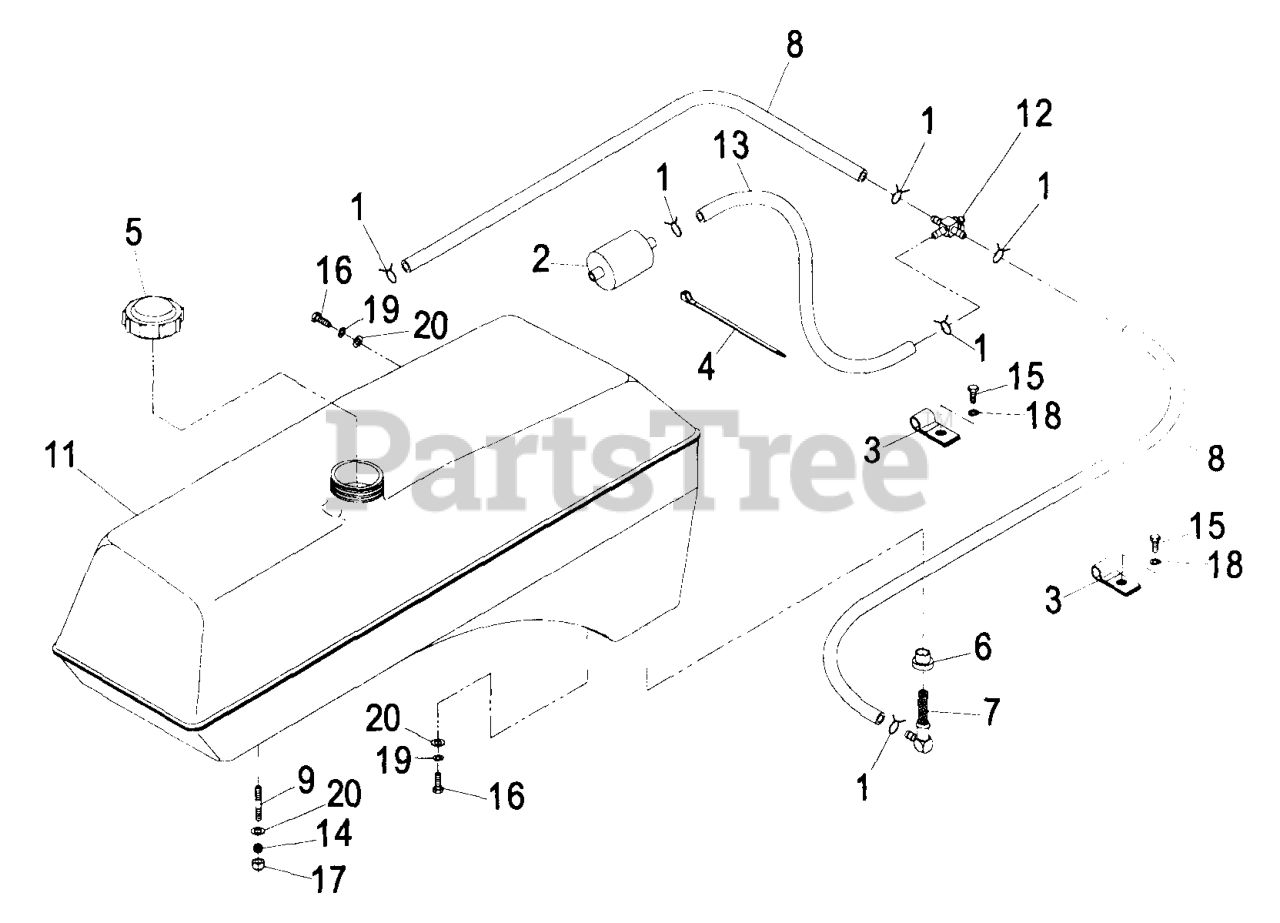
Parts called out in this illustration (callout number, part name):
2	Fuel Filter
3	CLIP-LOOM
4	TIE-PLASTIC
5	CAP-FUEL
7	ELBOW-TANK, FUEL
8	HOSE-FUEL
9	STUD
12	VALVE-FUEL
14	SPRING-TANK, FUEL
18	WASHER-LOCK
19	WASHER-LOCK
